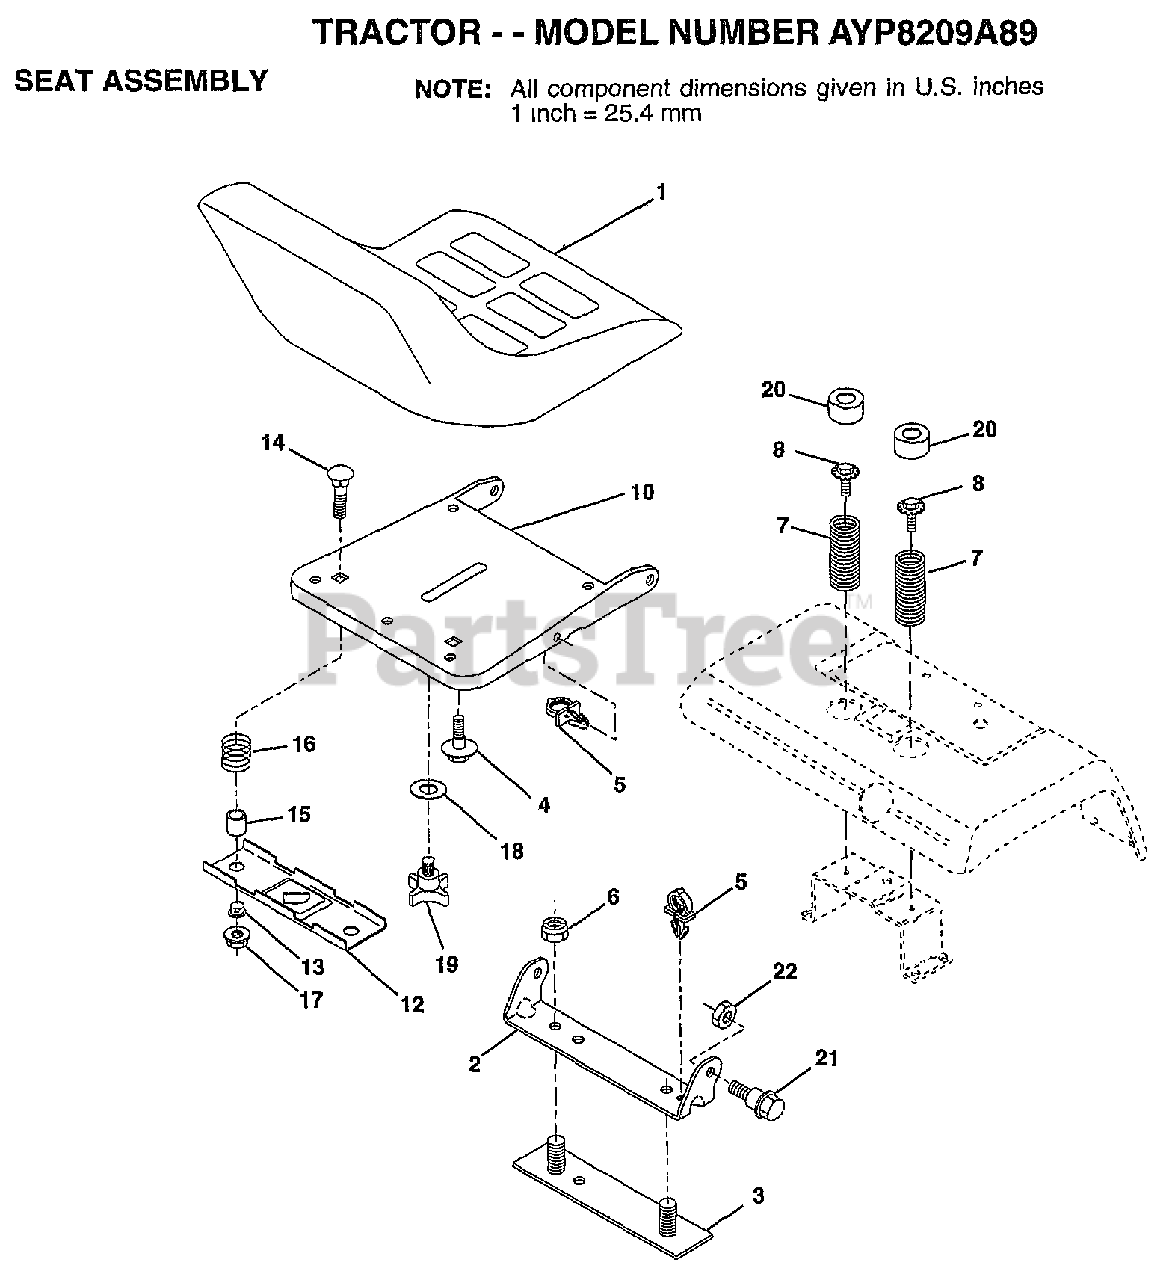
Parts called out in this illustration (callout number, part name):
2	BRACKET PVT SEAT
3	STRAP ASM FENDER
4	"BOLT,SHOULDER"
5	CLIP.PUSH-IN.HING
6	NUT
7	SPRING COMPRESSIO
8	BOLT.5/16-18.UNC
10	PAN-SEAT
12	BRKT SWITCH
13	BUSHING
14	BOLT-RD HD SQ NK
15	SPACER SPLIT
16	SPRING COMPRESSED
18	WASHER
19	"KNOB 1/2"" YT"
20	CAP SPRING
21	"BOLT,SHOULDER"
